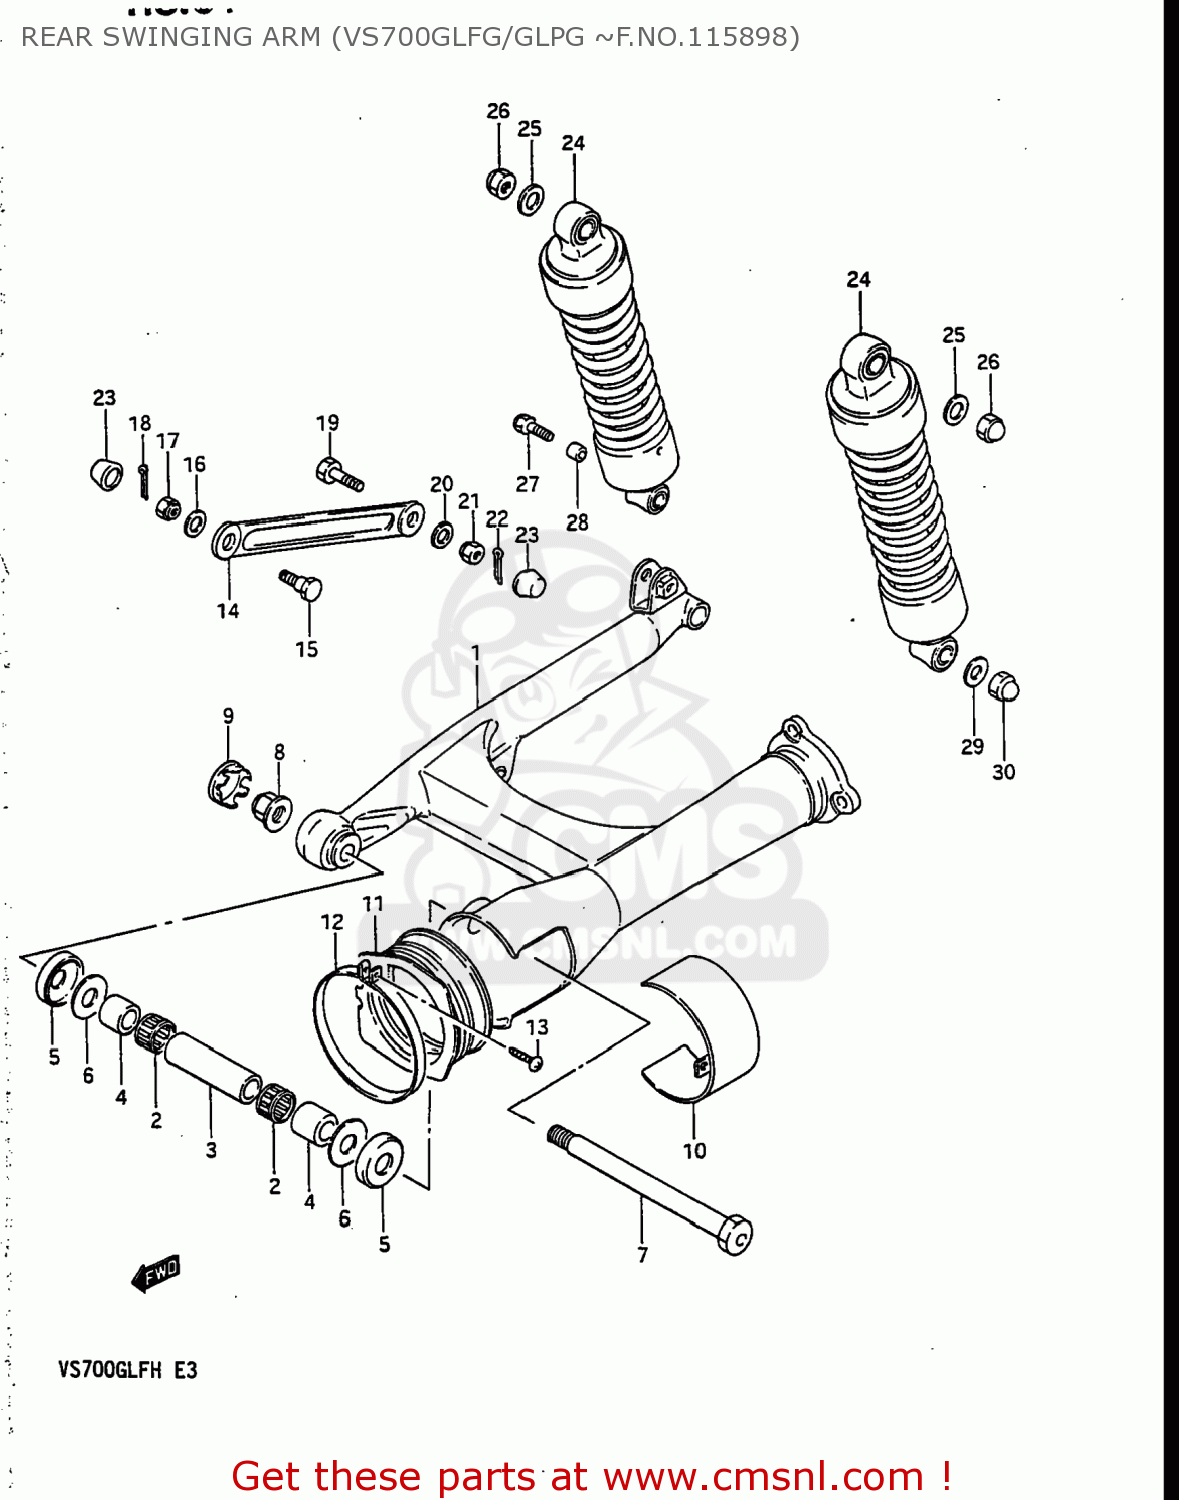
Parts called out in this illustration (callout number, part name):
1	SWING ARM ASSEMBLY,REAR
2	BEARING(22X29X20)
3	SPACER,REAR SWING ARM PIVOT
4	SPACER,RR SWGARM PIVOT
5	CVR,RR SWGARM DUST SEAL(OD:40)
6	WASHER
7	SHAFT,RR SWINGINGARM PIVOT
8	NUT
9	CAP,REAR SWING ARM PIVOT
10	COVER,REAR SWING ARM PIVOT
11	BOOT,PROPELLER SHAFT
12	CLAMP
13	SCREW 4X25
14	TORQUE LINK,REAR
15	BOLT(10X24.5)
16	WASHER (10.5X18X1)
17	NUT
18	PIN 16X20
19	BOLT 10X35
20	WASHER (10.5X18X1)
21	NUT
22	PIN 16X20
23	CAP
24	ABSORBER ASSEMBLY,REAR SHOCK
25	WASHER
26	NUT, LOWER LH
27	BOLT(10X36)
28	SPACER (10.2X14X20.7)
29	WASHER
30	NUT, LOWER LH
